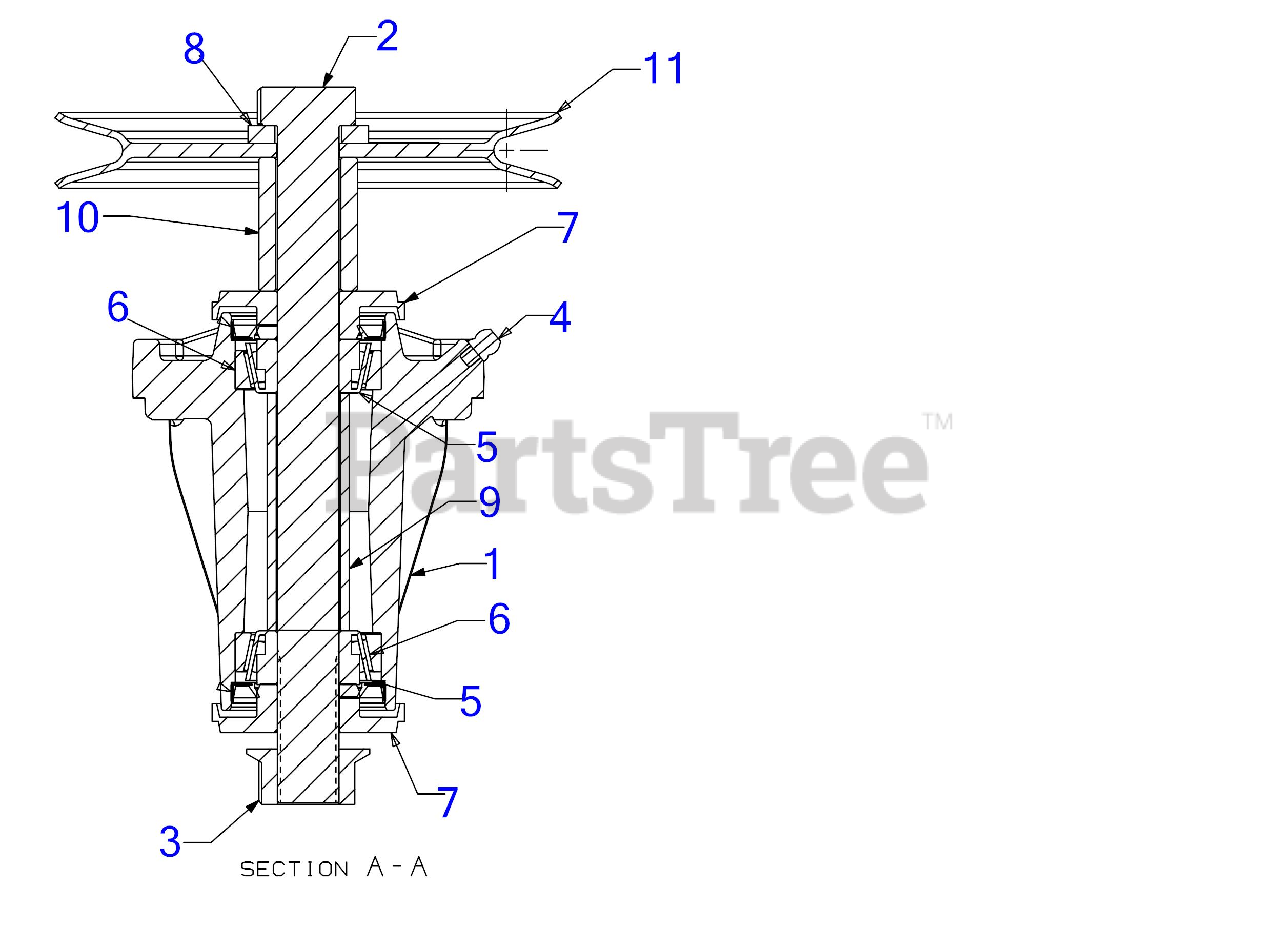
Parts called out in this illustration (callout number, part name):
1	HOUSING
2	SCREW 3/4-16 x 8.25 GR5
3	HEX FLANGE NUT 3/4
4	GREASE FITTING
5	BEARING CONE
6	BEARING CUP
7	DECK SPINDLE SPACER
8	SPACER .812 ID x .218 LG
11	V-PULLEY 6.107 DIA
